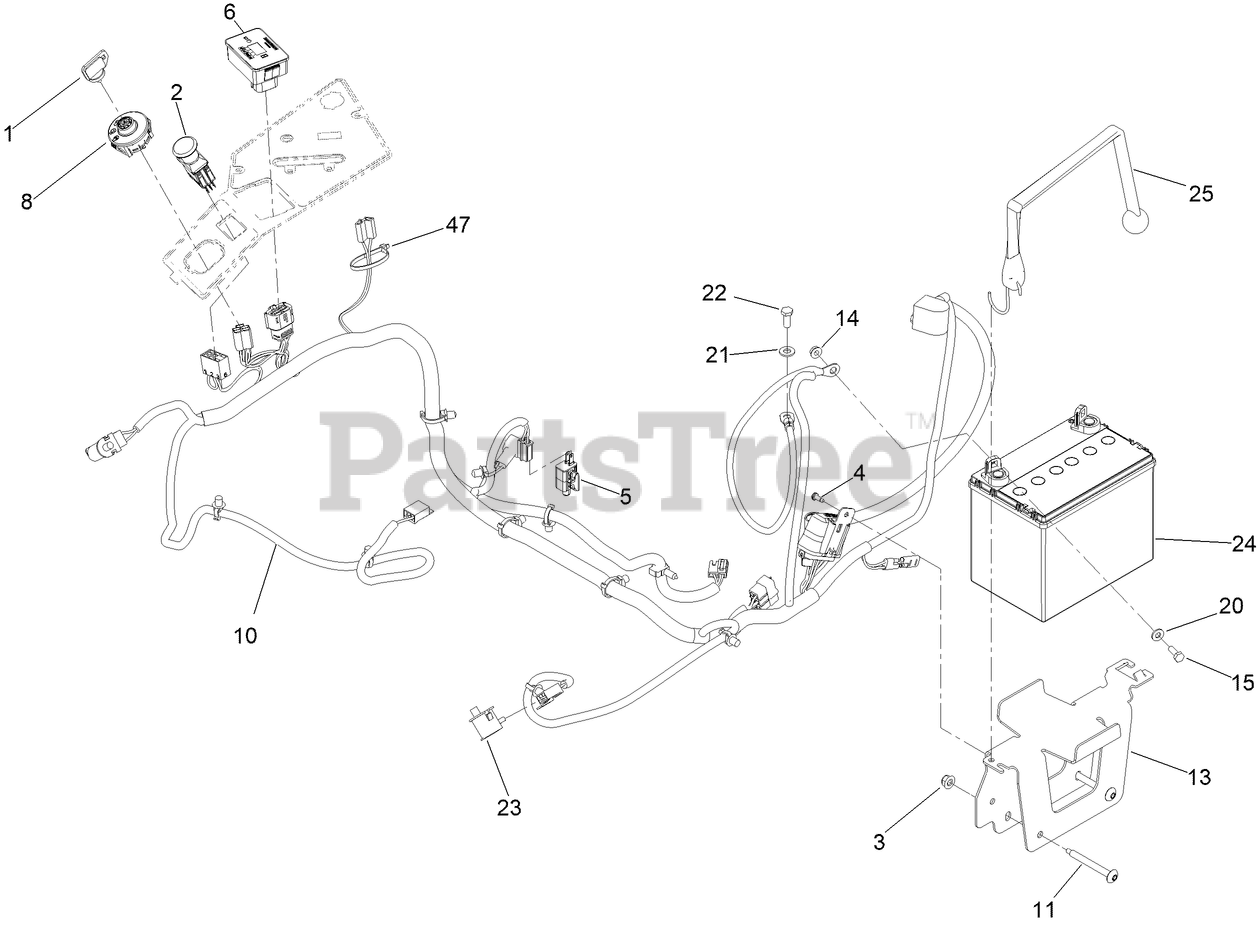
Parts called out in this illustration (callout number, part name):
1	KEY-IGNITION
2	SWITCH-PTO
3	NUT-HF, NI
4	SCREW-FORMING, THREAD
5	SWITCH
6	MODULE ASM
8	SWITCH-IGNITION
10	HARNESS-WIRE
11	SCREW-TORX
13	TRAY-BATTERY
14	NUT-HF
15	SCREW-HH
20	WASHER-FLAT
21	WASHER-PLAIN
22	SCREW-HH
23	SWITCH-BAIL
24	BATTERY
25	STRAP-BUNGEE
47	TIE-CABLE
